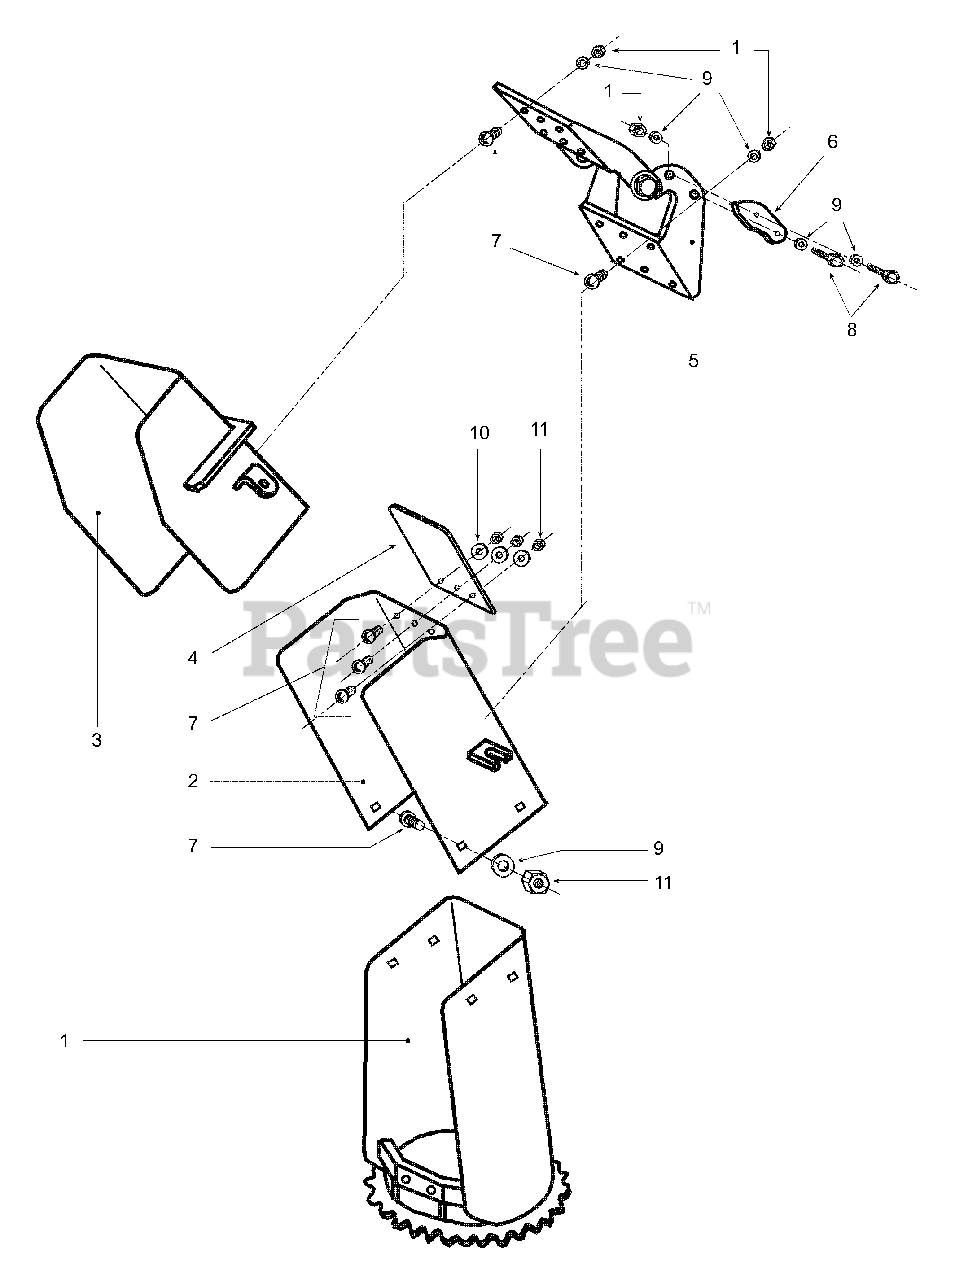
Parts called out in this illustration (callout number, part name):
1	Ejection Chimney
2	Intermediate Sector
3	Adjustable Flap
4	Rubber Plate
5	Complete Hinge For Flap
6	Flap Limit Stop
7	Roundhead Screw M6 x 16 - Din 603
8	Hexagonal Head Screw M6 x 18 - Din 933
9	Washer 6.4 x 12.5 x 1.6 - Din 125a
10	Washer 6.6 x 18 x 2 Uni 6593
11	Self Locking Nut M6 - Din 982
